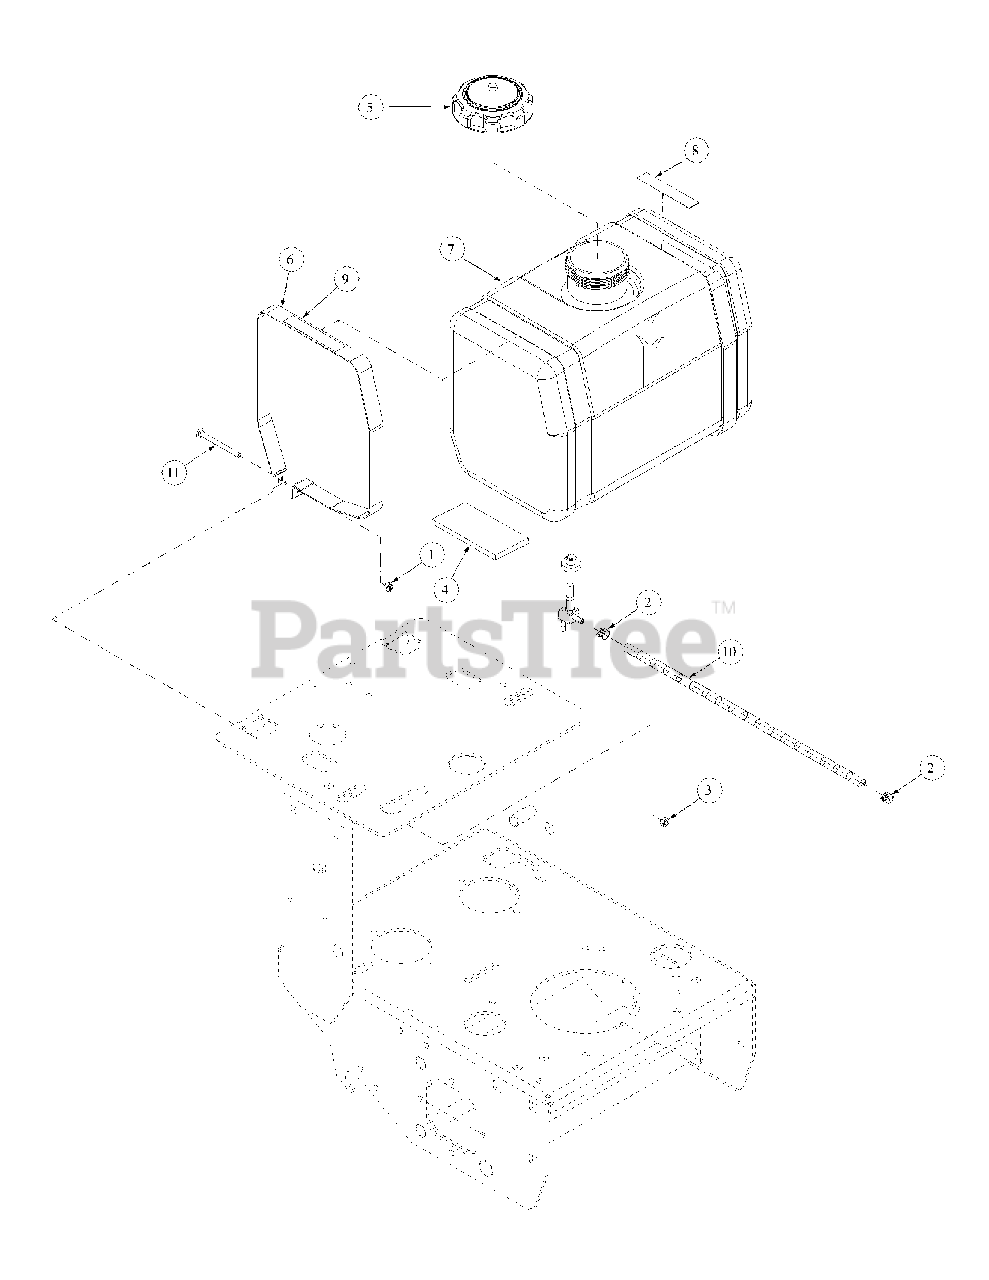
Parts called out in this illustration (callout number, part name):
1	Lock Nut, Nylon Insert, 1/4-20 Grade A
2	Uni-Clamp, #5077-136
3	Nut, 1/4-20, Grade A
4	Stop Pad, Rubber
5	Fuel Cap, 3.5
6	Fuel Tank Strap
7	Fuel Tank
8	Mower Warning Label, Turn Off Engine
9	Mower Instruction Label, Fuel Valve
10	18" Fuel Hose
11	Carriage Bolt, 1/4-20 x 3.00 Grade 5
